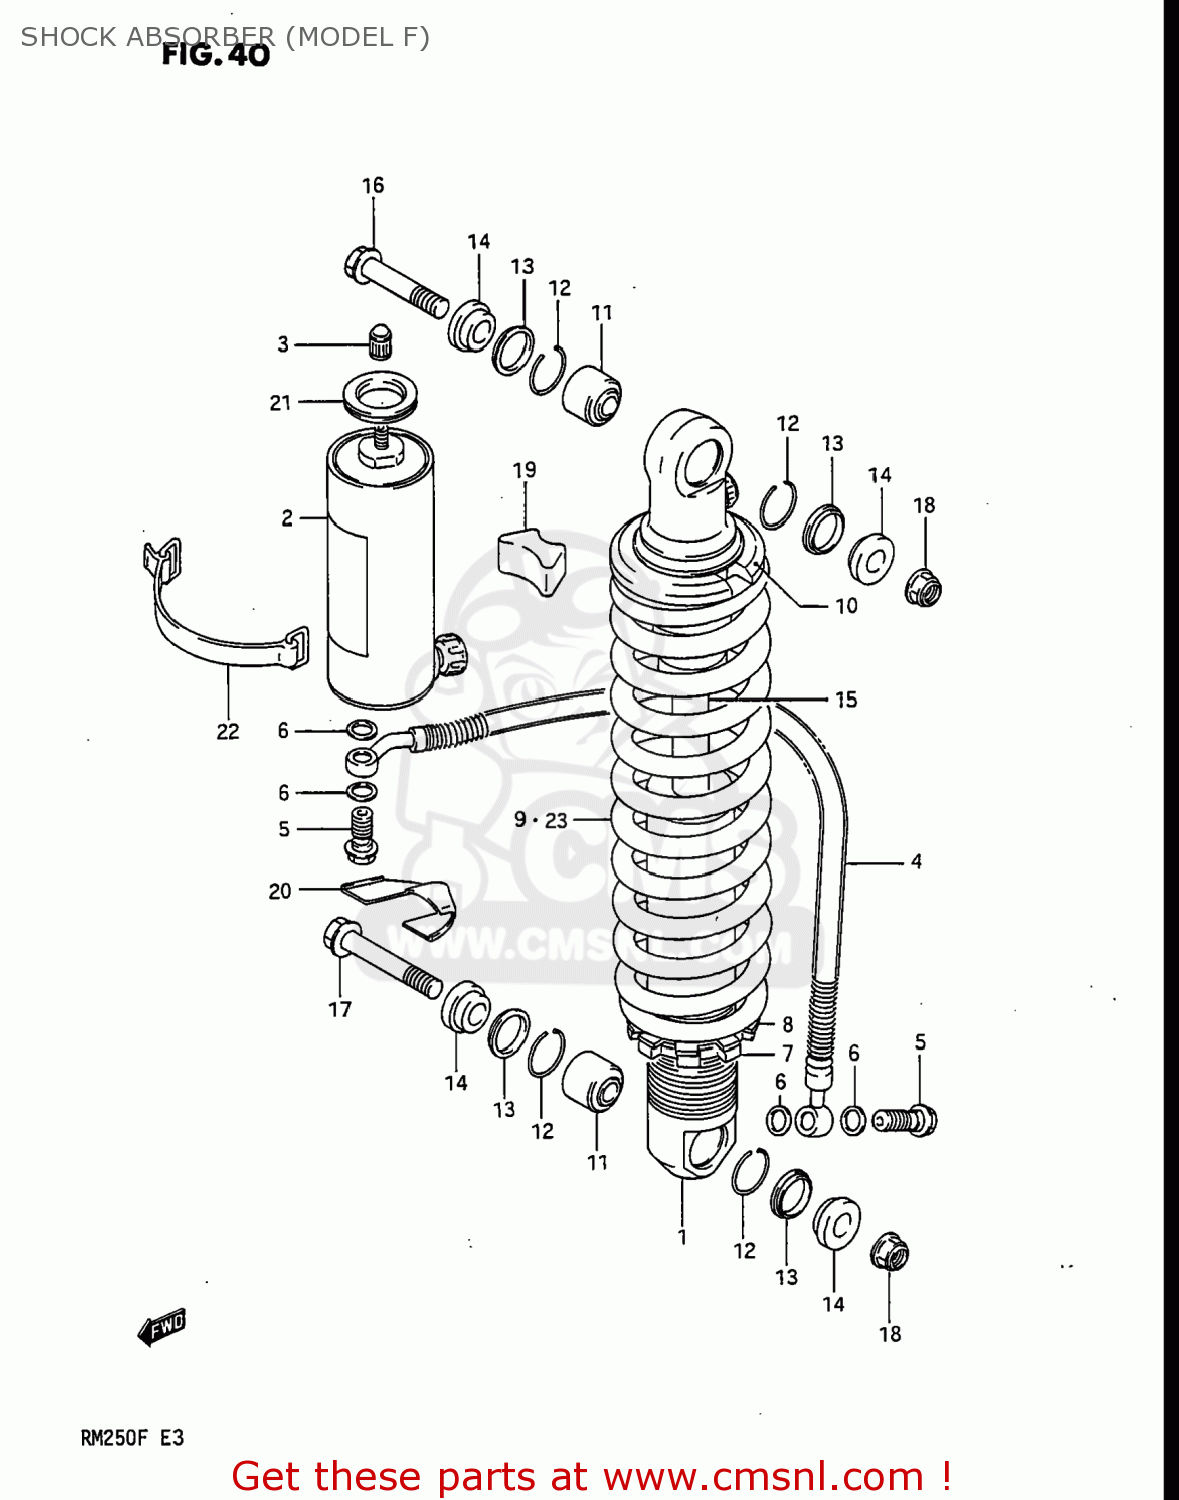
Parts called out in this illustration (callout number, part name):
1	ABSORBER ASSEMBLY,REAR SHOCK
2	RESERVE TANK,REAR SHOCK
3	CAP
4	HOSE,REAR SHOCK ABSORBER
5	BOLT,REAR SHOCK ABSORBER
6	GASKET (NAS)
7	GUIDE,REAR SHOCK ABSORBER SPRING
8	GUIDE,SPRING
9	SPRING
10	GUIDE,REAR SHOCK ABSORBER SPRING
11	BEARING,REAR SHOCK ABSORBER
12	RING
13	SEAL,DUST RR SHOCK ABSORBER
14	COLLAR
15	ROD,PISTON
16	BOLT,REAR SHOCK ABSORBER
17	BOLT(10X52)
18	NUT
19	CUSHION,RESERVOIR TANK
20	CUSHION,RESERVOIR TANK
21	CUSHION,RESERVOIR TANK
22	BAND
23	SPRING
